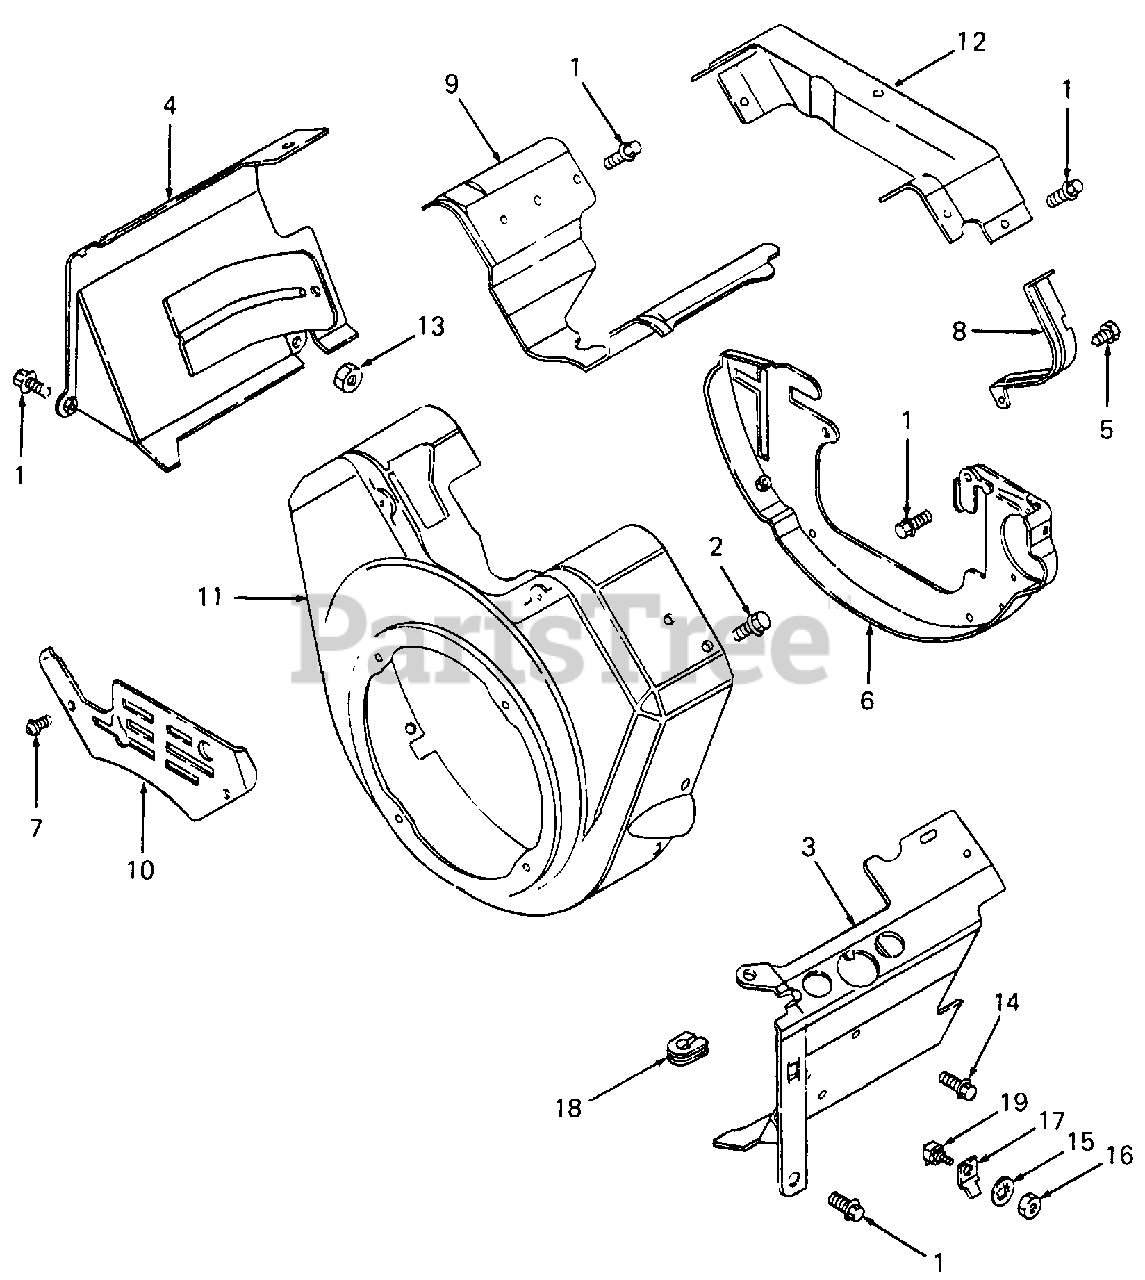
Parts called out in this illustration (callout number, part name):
1	Screw, Sems
2	Screw, Sems
3	Cover
4	Cover
5	Screw, Sems
6	Plate, Back
7	Screw, Sems
10	Cover, Carburetor
11	Housing, Blower
12	Cover, Valley Extension
13	Nut, Hex
14	Screw, Mtg
15	Washer, Lock, Internal Tooth
17	Terminal, Ground
18	Grommet, Cable
19	Insulator Assy
